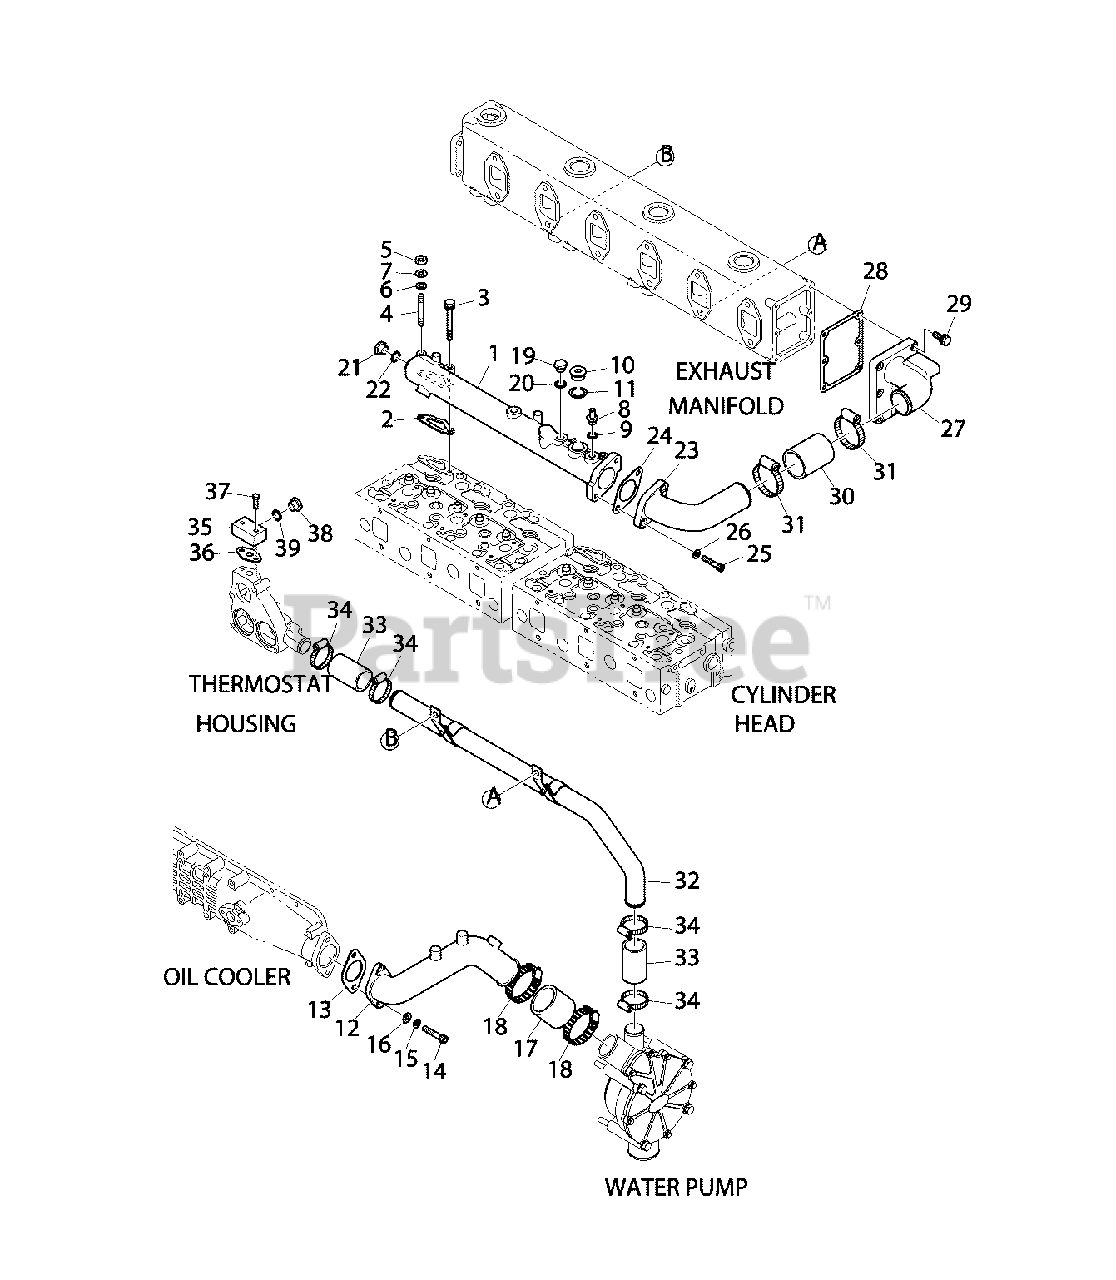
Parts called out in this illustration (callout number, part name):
1	* PIPE, WATER COOL
2	GASKET, WATER PIPE
3	* BOLT
4	* BOLT, STUD
5	* NUT, HEX
6	* WASHER, SPRING
7	* WASHER
8	* SCREW, CONNECT
9	SEAL, RING
10	* PLUG, SCREW
11	* SEAL, RING
12	* PIPE, WATER COOL
13	GASKET, WATER PIPE
14	* BOLT
15	* WASHER, SPRING
16	* WASHER
17	HOSE, COOLANT
18	CLAMP, HOSE
19	* SCREW, PLUG
20	* SEAL, RING
21	PLUG, SCREW
22	* SEAL, RING
23	* PIPE, WTR COOL
24	GASKET, WTR PIPE
25	* GASKET, WATER PIPE
26	* WASHER
27	* COVER, E/MNFLD
28	GASKET
29	* BOLT
30	HOSE, COOLANT
31	CLAMP, HOSE
32	* PIPE, WTR COOL
33	HOSE, COOLANT
34	CLAMP, HOSE
35	* ADAPTOR
36	GASKET, OIL PIPE
37	* BOLT
38	* PLUG, SCREW
39	* SEAL, RING
